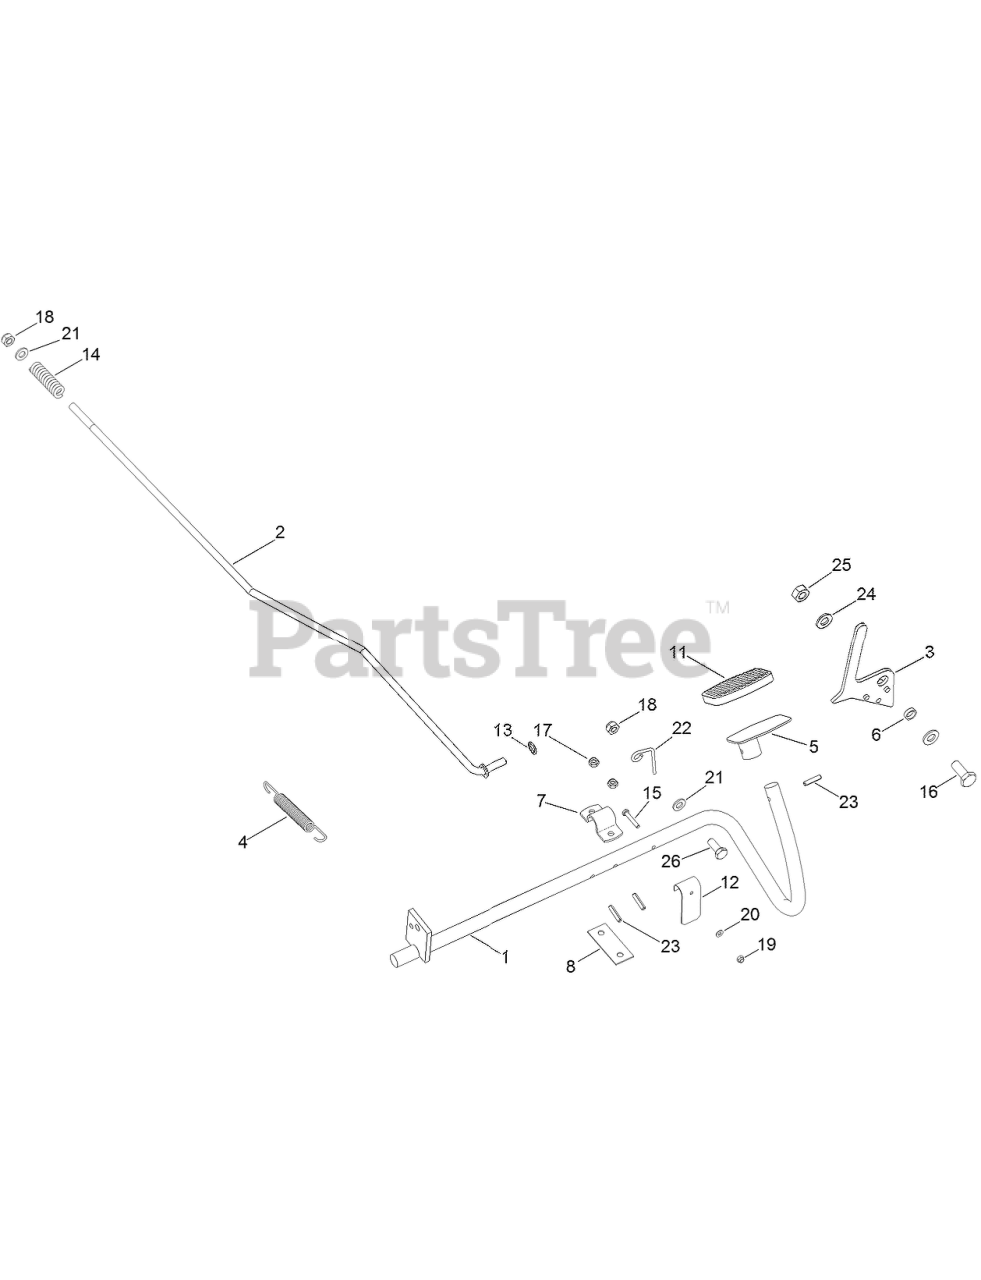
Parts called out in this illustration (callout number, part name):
2	ROD-BRAKE, LINKAGE
3	LEVER-PARKING BRAKE
4	SPRING
5	PEDAL-TRAVEL, BRAKE
6	SPACER
8	SPACER
11	PAD-PEDAL
12	BRACKET-PARKING BRAKE
13	WASHER
14	SPRING-BRAKE
15	SCREW-HEX
16	SCREW-HEX
17	NUT-LOCK
18	NUT-LOCK, NI
19	NUT-HEX
20	Washer
21	WASHER-PLAIN
22	SPRING-LEVER
23	PIN-SPRING
24	WASHER-FLAT
25	NUT-LOCK, NI
26	SCREW-HH
